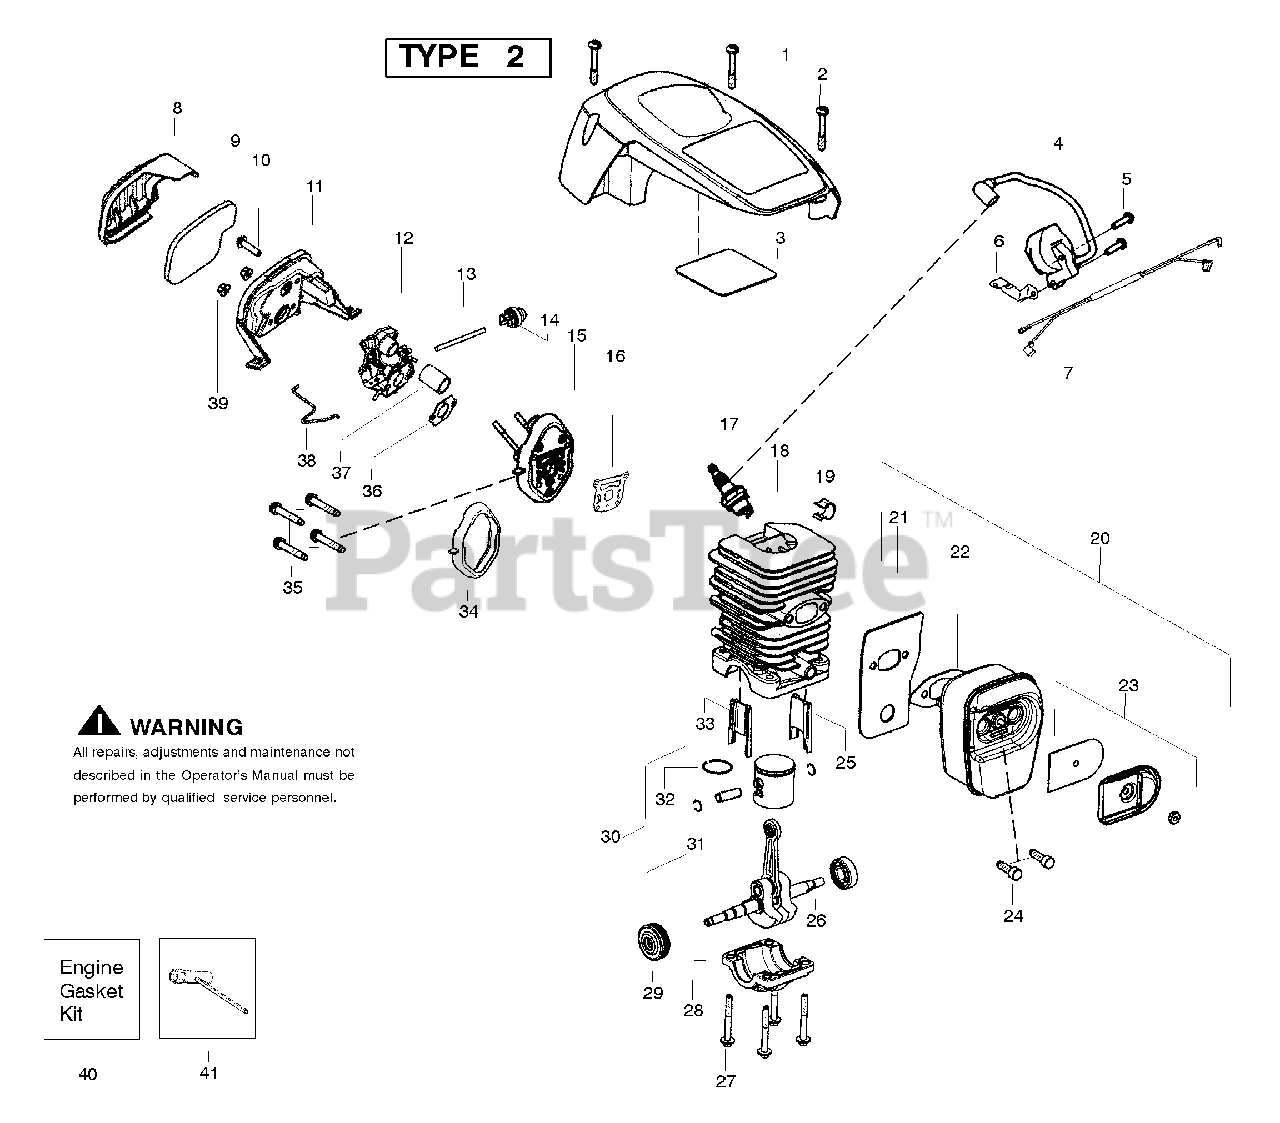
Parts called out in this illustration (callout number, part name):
1	Shield-Cylinder
3	Reflector-Tape
4	Module - Ignition
6	Strap-Ground
7	Assy-Wire Harness
8	Cover-Air Filter
9	Filter-Air
11	Housing-Air Filter
12	Assy-Carb. Walbro WTA30
12	Assy-Carb. Zama W-26B
13	Kit-Fuel Line
14	Bulb-Purge 'snap-in'
15	Kit-Carb. Adaptor
16	Gasket-cyl. o-ring
17	Accy-Spark Plug
18	Kit-Cylinder
19	Clip-High Tension Lead
20	Kit-Muffler
21	Backplate-Muffler
22	Gasket-Muffler
23	Kit-Spark Arrestor
24	Bolt-Muffler
25	Insert-Left Cyl.
26	Assy-Crankshaft/Rod
28	Cap-Crankcase
29	Assy-Bearing/Seal
30	Kit-Piston
31	Retainer-Piston Pin
32	Ring-Piston
33	Insert-Right Cyl.
34	Seal-Adaptor
36	Gasket-Carb.
37	Tube-Intake
38	Wire-Throttle
39	Nut-Carb.
40	Kit-Gasket
41	Wrench-Bar
